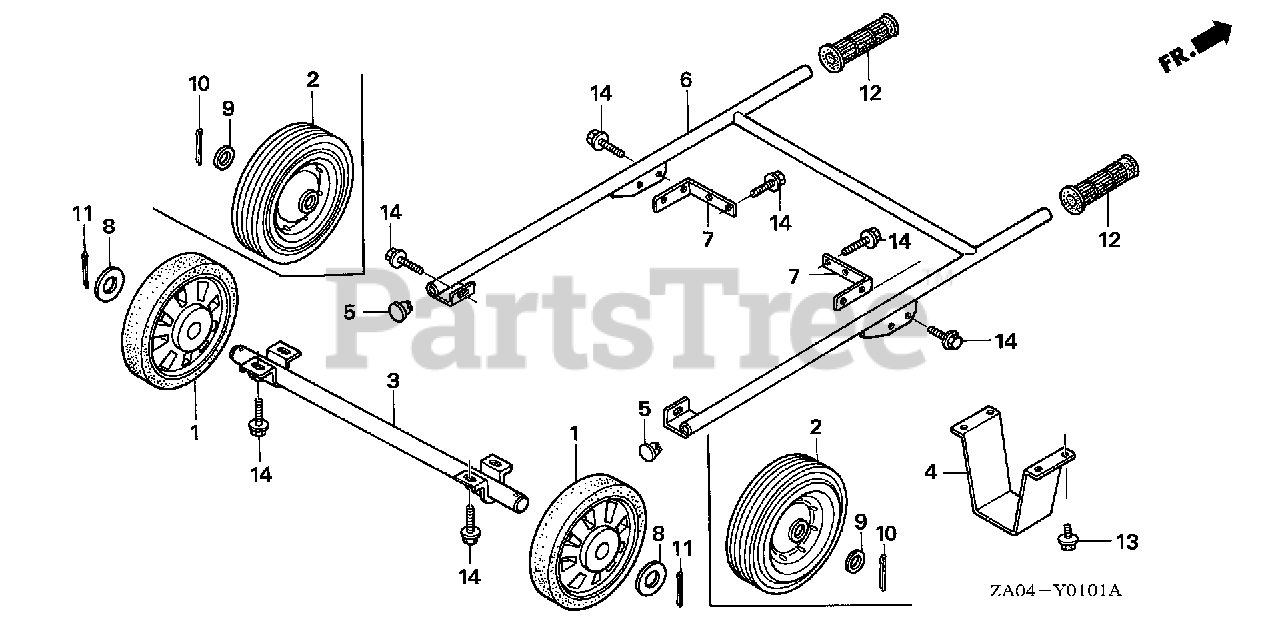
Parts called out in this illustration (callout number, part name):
1	WHEEL
3	SHAFT, WHEEL
4	STAND
5	CAP, HANDLE (LOWER)
6	PIPE, HANDLE *NH105* (MAT BLACK)
7	STAY, HANDLE
8	WASHER, PLAIN (24MM) (NOT AVAILABLE)
11	PIN, SPLIT (5.0X40)
12	GRIP D, R. HANDLE
13	BOLT, FLANGE (6X10)
14	BOLT, FLANGE (8X14)
